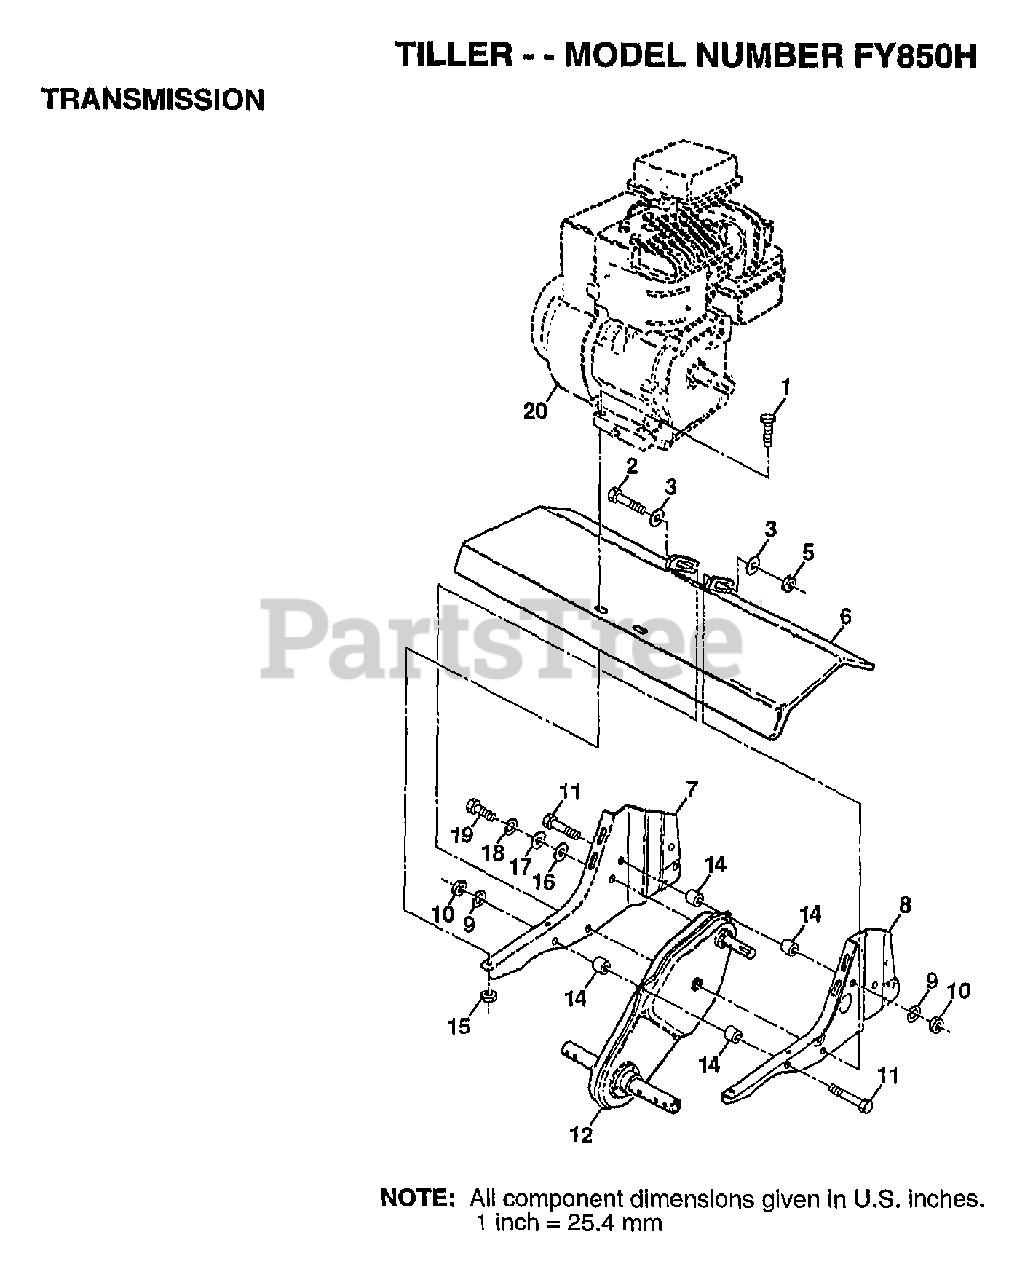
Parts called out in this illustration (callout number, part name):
1	BOLT.HEX.5/16-1.5
2	BOLT HEX 3/8-16
3	WASHER
5	NUT
6	"SHIELD, TINE"
7	BRACKET.ENGINE.RH
8	ENGINE BRKT LH TI
9	LOCKWASHER
10	NUT.HEX.5/16-18
14	SPLIT SPACER RT
16	WASHER
17	WASHER
18	LOCKWASHER
19	BOLT
